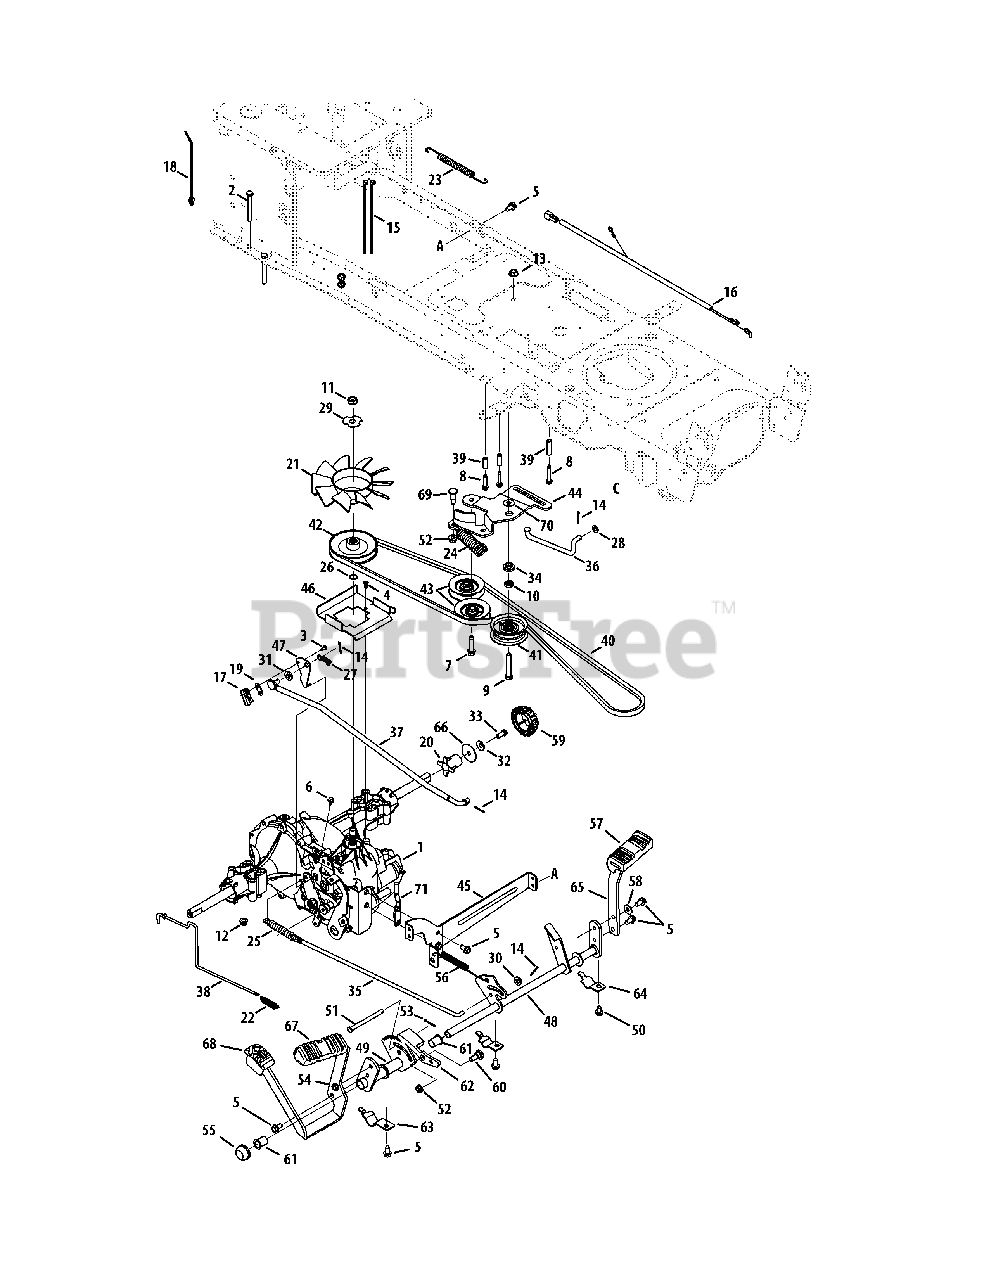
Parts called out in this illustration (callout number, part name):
1	Transmission
2	Hex Screw, 5/16-18, 2.75, Gr5, Std
3	Screw, #8-18, 0.500,
4	Screw, #10-16, 0.500
5	Screw, Self-tapping, 5/16-18, .750
6	Screw, Self-tapping, 1/4-20, 0.375
7	Screw, Self-tapping, 3/8-16, 1.500
8	Screw, Self-tapping, 1/4-20, 1.625
9	Hex Screw, 3/8-16, 2.25, Gr5
10	Nut, Jam, 7/16-20, Gr2
11	Nut, Jam Lock, 1/2-20, Gr5, Nylon
12	Nut, Flange Lock, 5/16-18, Nylon
13	Nut, Flange Lock, 3/8-16
14	Pin, Cotter, 3/32, 1.0
15	Cable, Tie, 3/16 x .05 x 7.4
16	Jumper Harness, Ground & Reverse
17	Switch, Spring, Short
18	Tie, Cable, Push Mount 7.5
19	Plate, Insulator Nut
20	Sleeve, .765 Id x 1.500
21	Fan, Hydro
22	Spring, Extension, .48 Od x 2.03
23	Spring, Extension, .500 Dia x 12.6
24	Spring, Extension, 1.00 Dia x 4.75
25	Spring, Extension, .59 Od x 4.00
26	Ring, Wire
27	Spring, Extension, .375 Od x 1.44
28	Washer, Flat, .330 x .630 x .0635
29	Washer, Lock, Transmission Hydro
30	Washer, Flat, .344 x .750 x .120
31	Washer, Flat, .407x.812x.135, Ht
32	Washer, Bell, .340 x .872 x .060
33	Hex Screw, 5/16-24, .750, Gr5, Lock
34	Spacer, Shoulder, 1.375 x .380 x .183
35	Rod, Brake, LT Hydro
36	Rod, Transmission, Bypass
37	Rod, Control, Hydro
38	Rod, Hydro Bypass
39	Spacer, .260 x .372 x 1.420
40	Belt, V-Type
41	Pulley, Idler, Flat 2.75 OD
42	Pulley, Input, 4.13 Dia
43	Pulley, Idler, V-Type x 3.06
44	Bracket, Idler, Center Double
45	Bracket, Mount, Hydro
46	Bracket, Support, Belt Disengage
47	Bracket, Actuator, Switch
48	Control Assembly, Brake
49	Bracket Assembly, Pedal, Hydro
50	Screw, Self-tapping, 5/16-18, 0.625,
51	Pin, Clevis, 5/16 x 3.985
52	Nut, Flange Lock, 3/8-16, Nylon
53	Pin, Cotter, Bow-Tie 72
54	Bracket, Pedal, Hydro
55	Cap, Push 5/8
56	Spring, Extension, .63 Dia x 4.95
57	Pad, Pedal, Brake
58	Washer, Bell, .340 x .872 x .060
59	Cap, Hub
60	Bolt, Shoulder, .500 x .270, 3/8-16
61	Bearing, Flange, .630 x .695 x .60
62	Latch, Cruise
63	Bracket, Support, Pedal Strap
64	Bracket, Support, Pedal Strap 5/8
65	Bracket, Pedal, Brake
66	Washer, Flat, .350 x 1.59 x .062
67	Pad, Pedal, Forward
68	Pad, Pedal, Reverse
69	Scr, Shldr, .50 x .685 3/8-16
70	Washer, Flat, .385 x 1.0 x .030
71	Belt Keeper Rod
